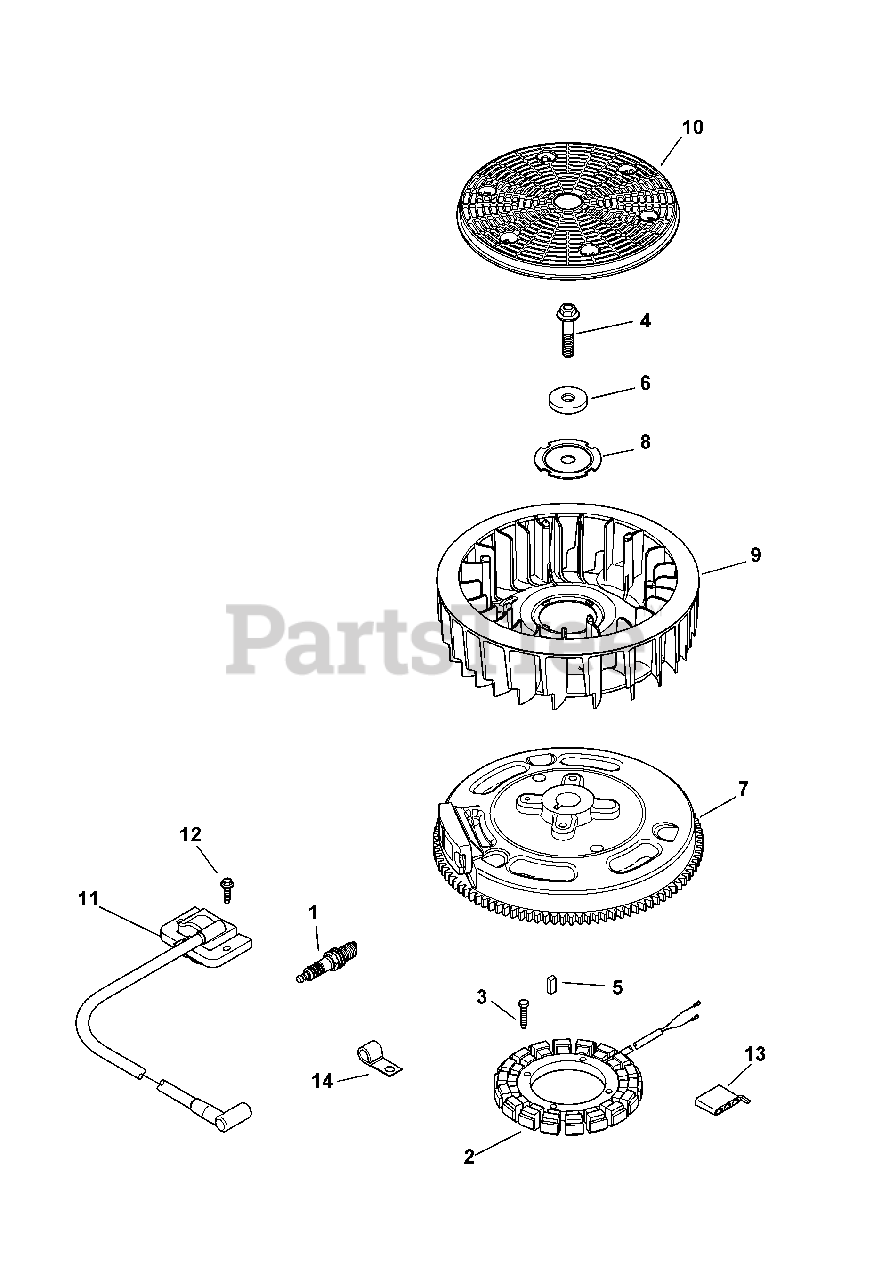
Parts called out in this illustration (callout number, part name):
1	Spark Plug
2	15 Amp Stator Kit
3	Screw, M5 x 0.8 x 25
4	Hex Flange Screw
7	Flywheel Assembly
8	Fan Mounting Plate
9	Fan
11	Module Ignition Kit
12	Screw, M5 x .8 x 20
